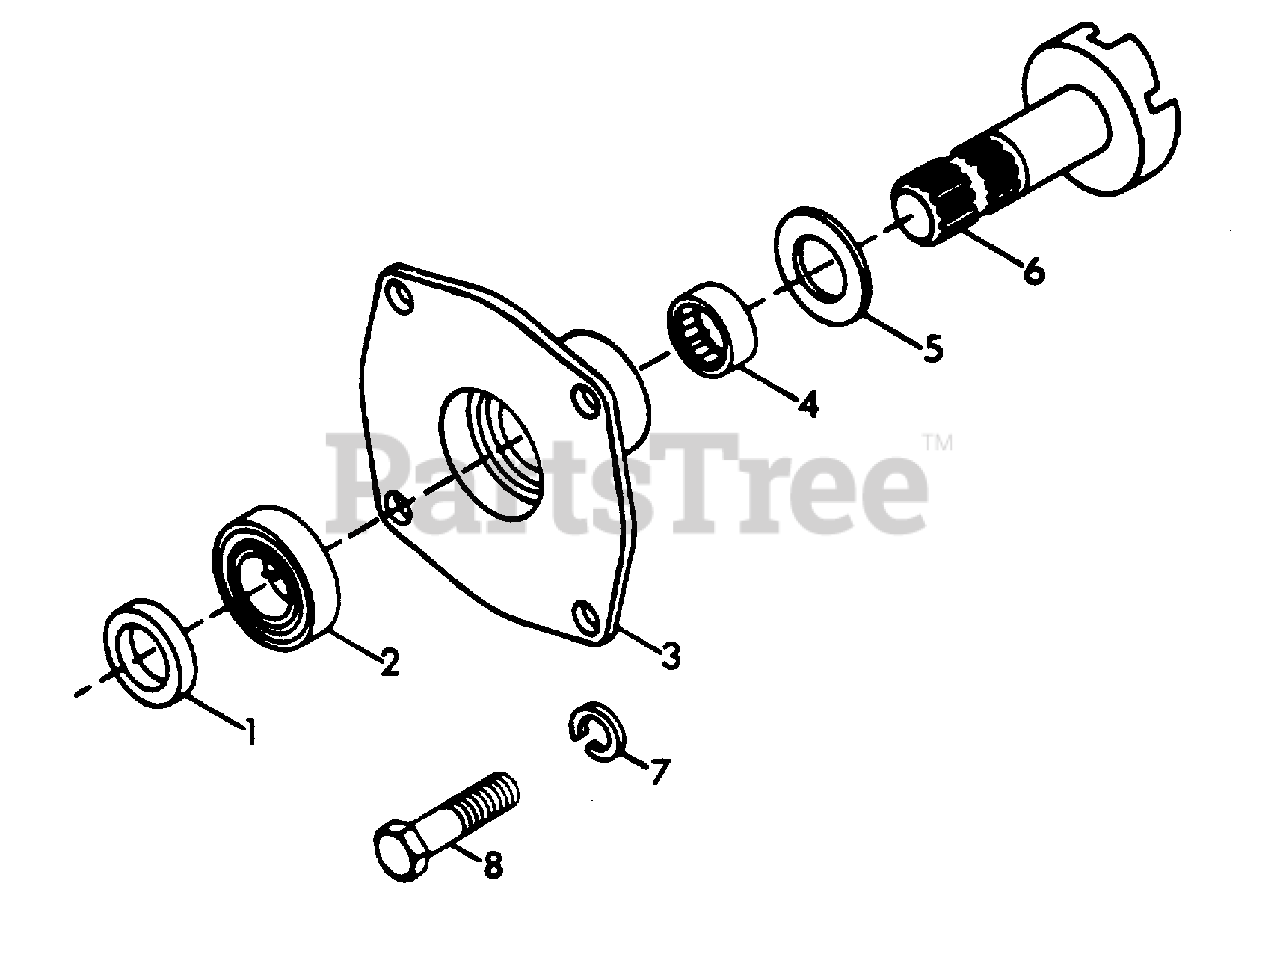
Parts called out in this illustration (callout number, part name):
1	RING, RETAINING .978X1.5X3
2	BEARING, BALL 1.000X2.000X.562
3	PLATE, COVER ADVANCE CASTING
4	BEARING, NEEDLE 1.000X1.250X2.000
5	BEARING, THRUST 1.012X1.750X.125
6	SHAFT, PTO DOG CLUTCH
7	WASHER, LOCK 1/2 REG.
8	BOLT, HEX 1/2-13X1.50
